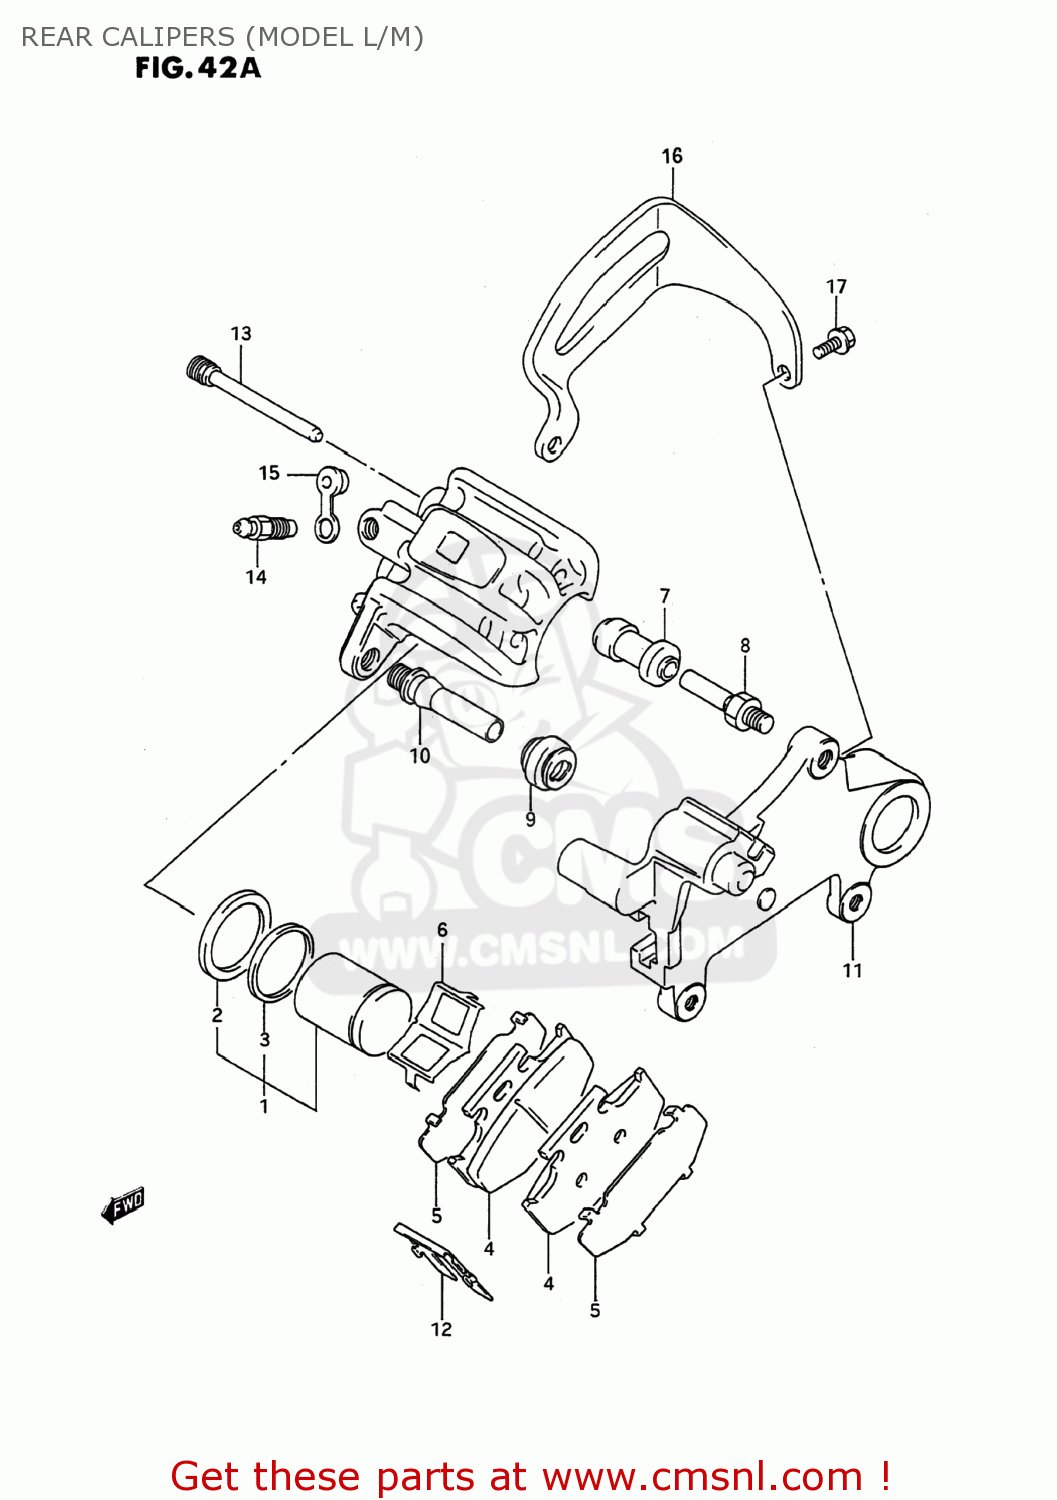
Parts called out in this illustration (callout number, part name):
1	PISTON SET
2	SEAL,PISTON
3	SEAL,DUST
4	PAD
5	SHIM
6	SPRING,PAD
7	BOOT
8	PIN,BOLT
9	BOOT
10	PIN
11	BRACKET
12	RETAINER
13	PIN,HANGER
14	BLEEDER
15	CAP,BLEEDER
16	GUARD,RR CALIPER
17	BOLT
